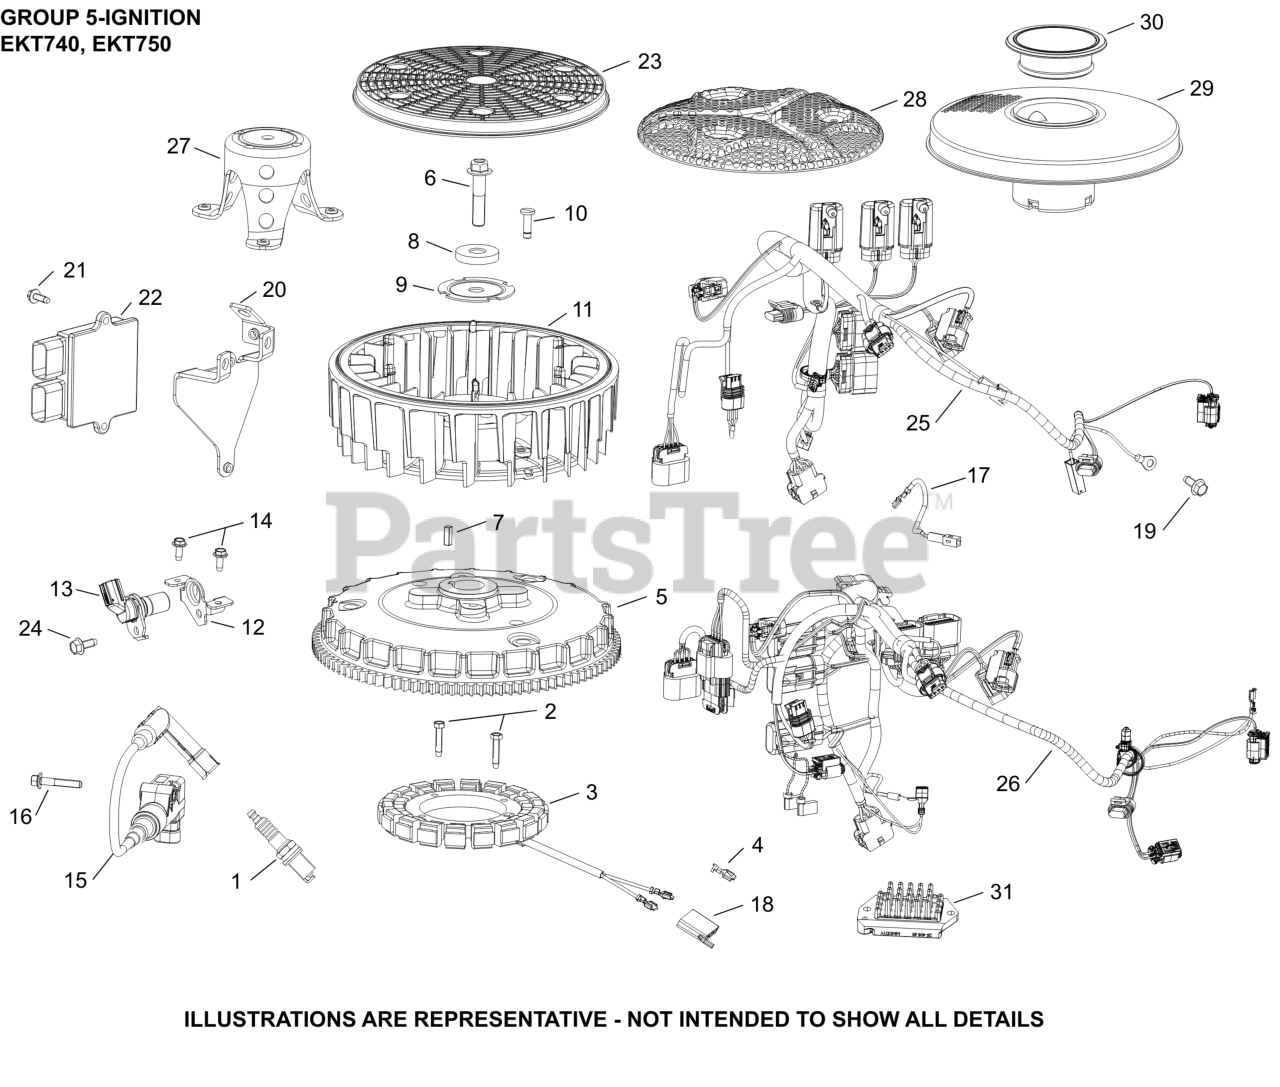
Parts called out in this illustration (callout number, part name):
1	SPARK PLUG, RFI
2	SCREW, THREAD FORMING
3	KIT, 15 / 20 AMP STATOR
5	FLYWHEEL, ASSEMBLY
6	SCREW, HEX FLANGE
7	KEY, SQUARE
8	WASHER, FLAT
9	PLATE, FAN MOUNTING
10	RETAINER, FLYWHEEL FAN
12	BRACKET, SENSOR
13	SENSOR, SPEED
15	COIL, IGNITION - EFI (RFI/EMC)
17	LEAD, REGULATOR RECTIFIER JUMPER
18	CONNECTOR
20	BRACKET, ECU
21	SCREW, THREAD FORMING
23	SCREEN, GRASS
24	SCREW, THREAD FORMING
25	HARNESS, WIRING ASSEMBLY (RECOIL)
NI	SCREW, THREAD FORMING
NI	SCREW, HEX FLANGE
NI	MODULE, ECU
NI	WASHER, INT TOOTH LOCK #10
